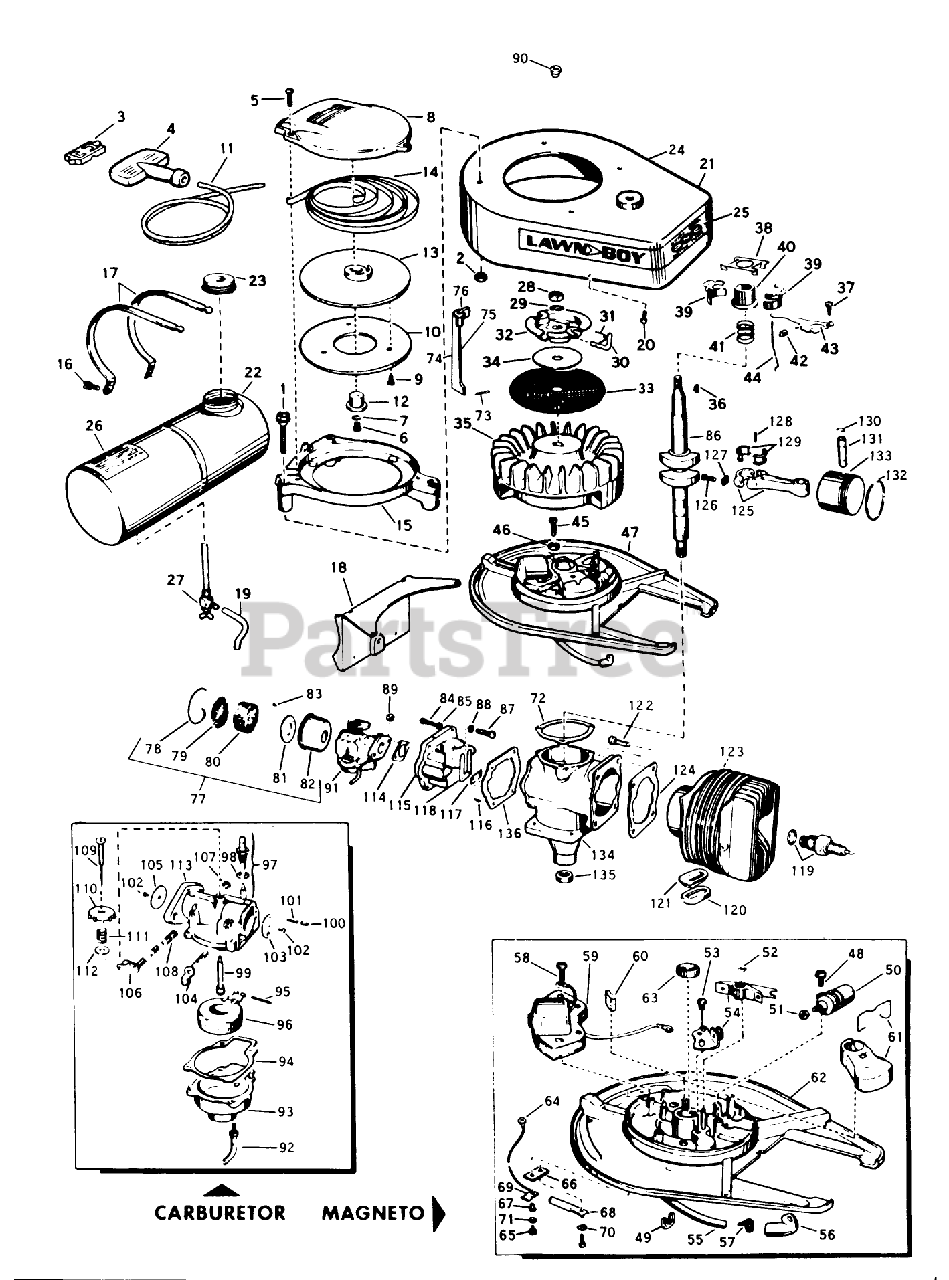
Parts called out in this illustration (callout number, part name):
14	RECOIL SPRING
20	SCREW S
27	VALVE&SCREEN SM
30	PIN - STARTER
40	COLLAR S
42	WEAR BLOCK S
43	GOVERNER LEVER AY
44	GOVERNOR ROD S
45	Screw-Crankcase to Arm. Plate
46	SCREW S
54	BREAKER AY. S
56	Cover-Rubber
65	Screw Shut-off Switch
70	Washer, Bow
72	GASKET S
73	Cotter Pin
80	ELEMENT
81	BACK-UP PLATE
84	SCREW S
87	Screw-Reed Plate to Carb.
89	STOP NUT
102	Screw-Choke Disc
108	SPRING
109	NEEDLE AY. S
111	Spring-Ndl. Adj.
114	GASKET S
117	PLATE-BACKUP, REED
119	Spark Plug
120	GASKET S
124	GASKET S
129	LINER ASM
130	RING-RETAINING
